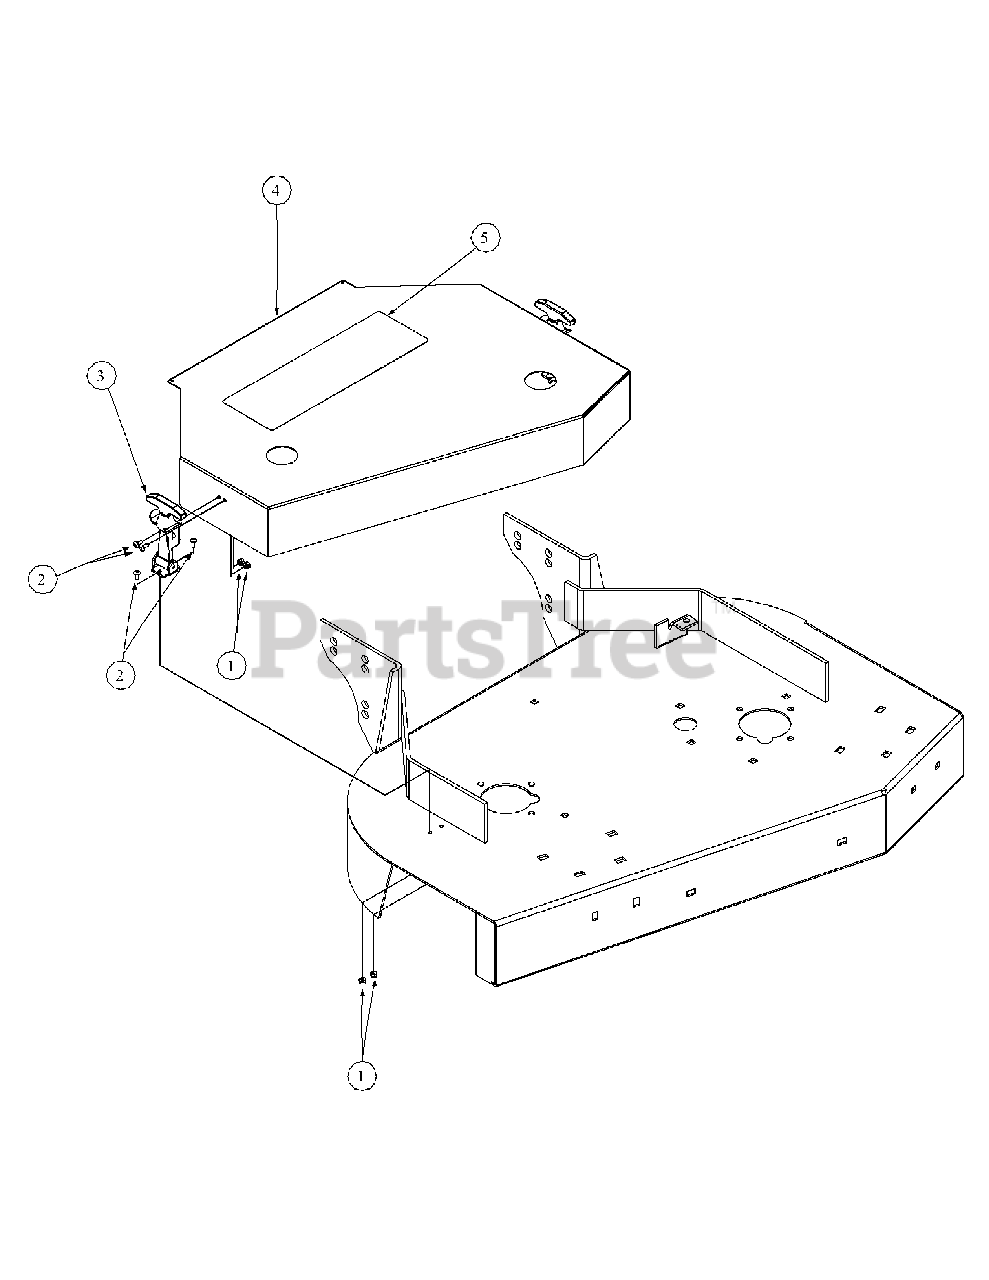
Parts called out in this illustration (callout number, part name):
1	Lock Nut, Nylon Insert
2	Machine Screw, 10-24 x 1/2
3	Rubber Hood Latch
4	Deck Cover, 36
5	Decal 36 MTD
